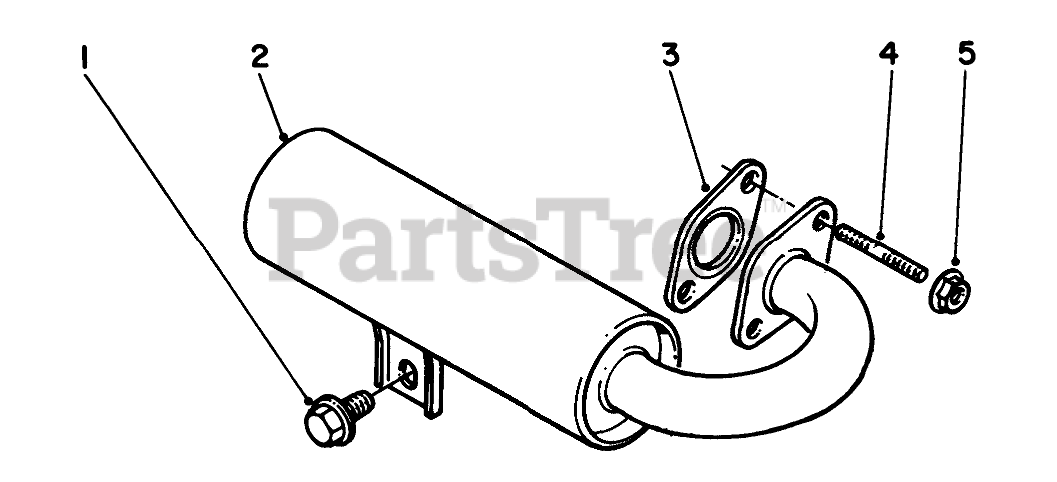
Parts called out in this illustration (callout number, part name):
2	Muffler
3	Gasket-Exhaust
4	Bolt-Stud
